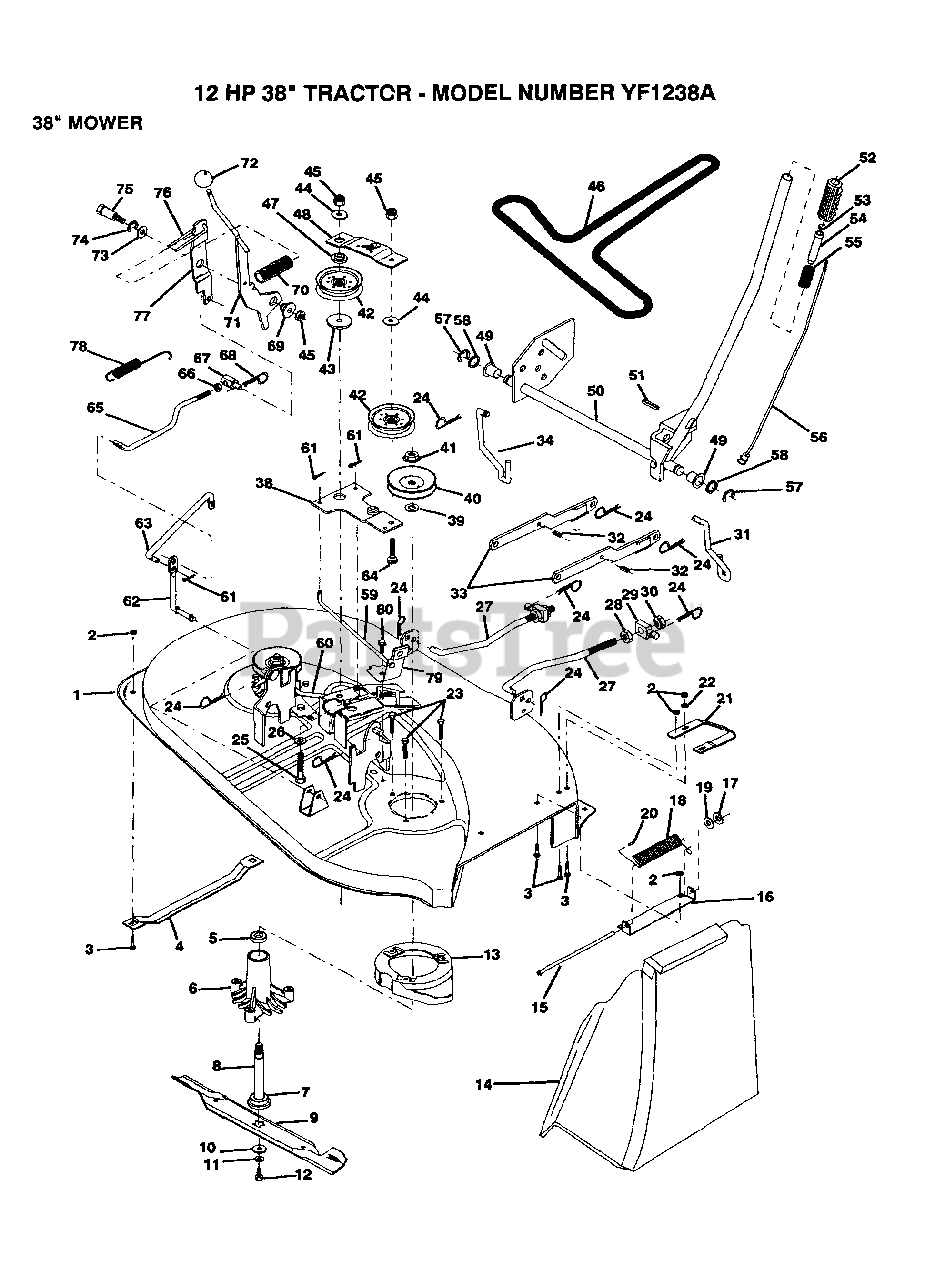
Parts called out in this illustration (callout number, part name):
3	BOLT
4	RUNNER-LH M
5	BEARING
6	HSG ASM MANDREL
7	BEARING.BALL
10	WASHER BLADE
12	BLADE BOLT
14	DEFLECTOR-SHLD T
15	ROD-HINGE T
17	NUT PUSH M
19	WASHER
20	CAP-SLEEVE LT
21	RUNNER RH
22	WASHER M
25	BOLT
26	WASHER GT
27	LINK.FRONT
28	NUT
29	TRUNION
30	NUT.LK.W/WSH.1/2.
31	LIFT LINK RH
32	"PIN,SPRING"
34	LINK LIFT LH
38	IDLER ARM ASSY
39	WASHER
42	FLAT IDLER PULLEY
43	SPACER RETAINER
44	WASHER GT
46	BELT-V.88.12.MW
47	RETAINER SPACER
48	IDLER ARM STIFF
49	NYLON BEARING
51	PIN-GROOVE LT
52	GRIP
58	WASHER
59	BRAKE ROD RH
60	BRAKE ROD LH
62	PIVOT ROD
63	CLUTCH ROD SECOND
64	BOLT
66	NUT
67	TRUNION
68	RETAINER M
69	BUSHING
71	CLUTCH ARM PRI AS
72	KNOB T (1/2-HOLE)
73	WASHER
74	RING
75	SHOULDER BOLT
76	SPRING KEEPER
77	CLUTCH ARM SECOND
78	RETURN SPRING
79	BRAKE ASM
80	SCREW
